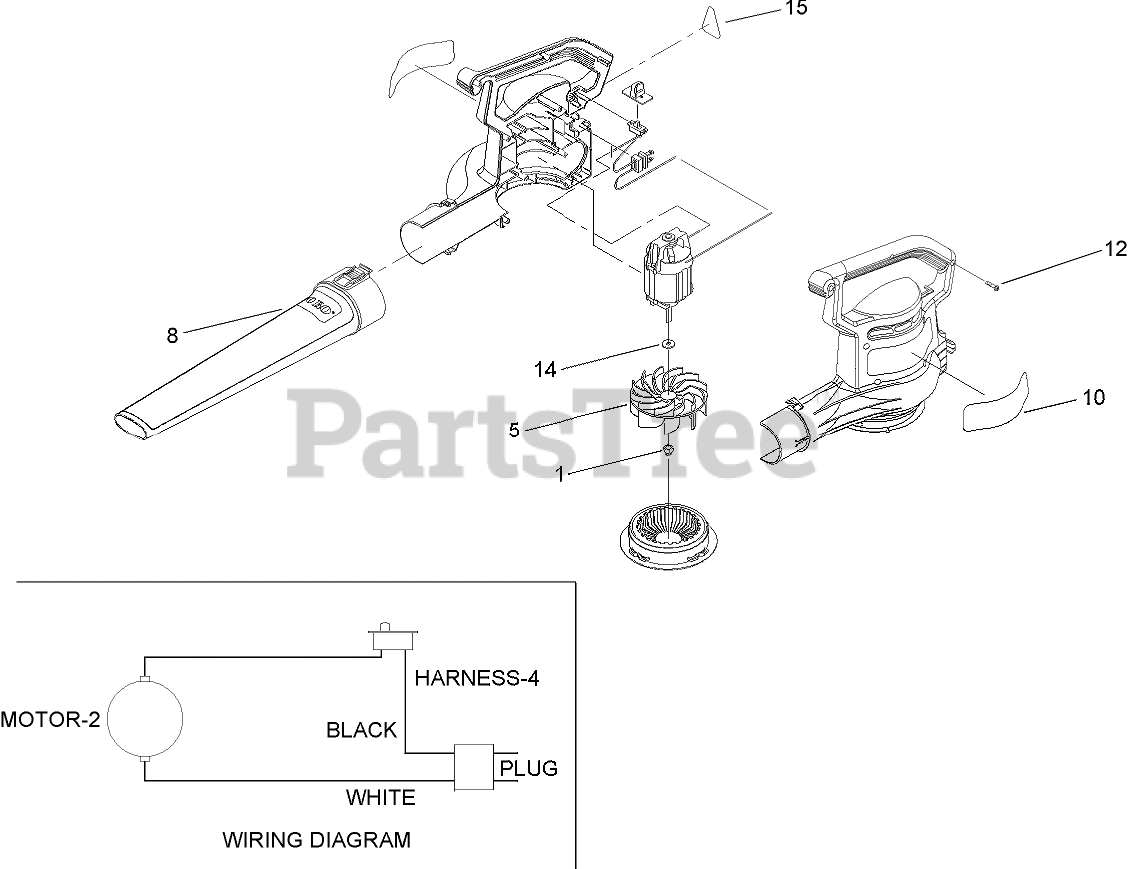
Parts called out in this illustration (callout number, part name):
1	NUT-LOCK, NI
5	IMPELLER, BLOWER
8	TUBE - BLOWER SHORT
10	DECAL - POWER SWEEP
12	SCREW-PPH
14	WASHER
15	DECAL - INFORMATION
